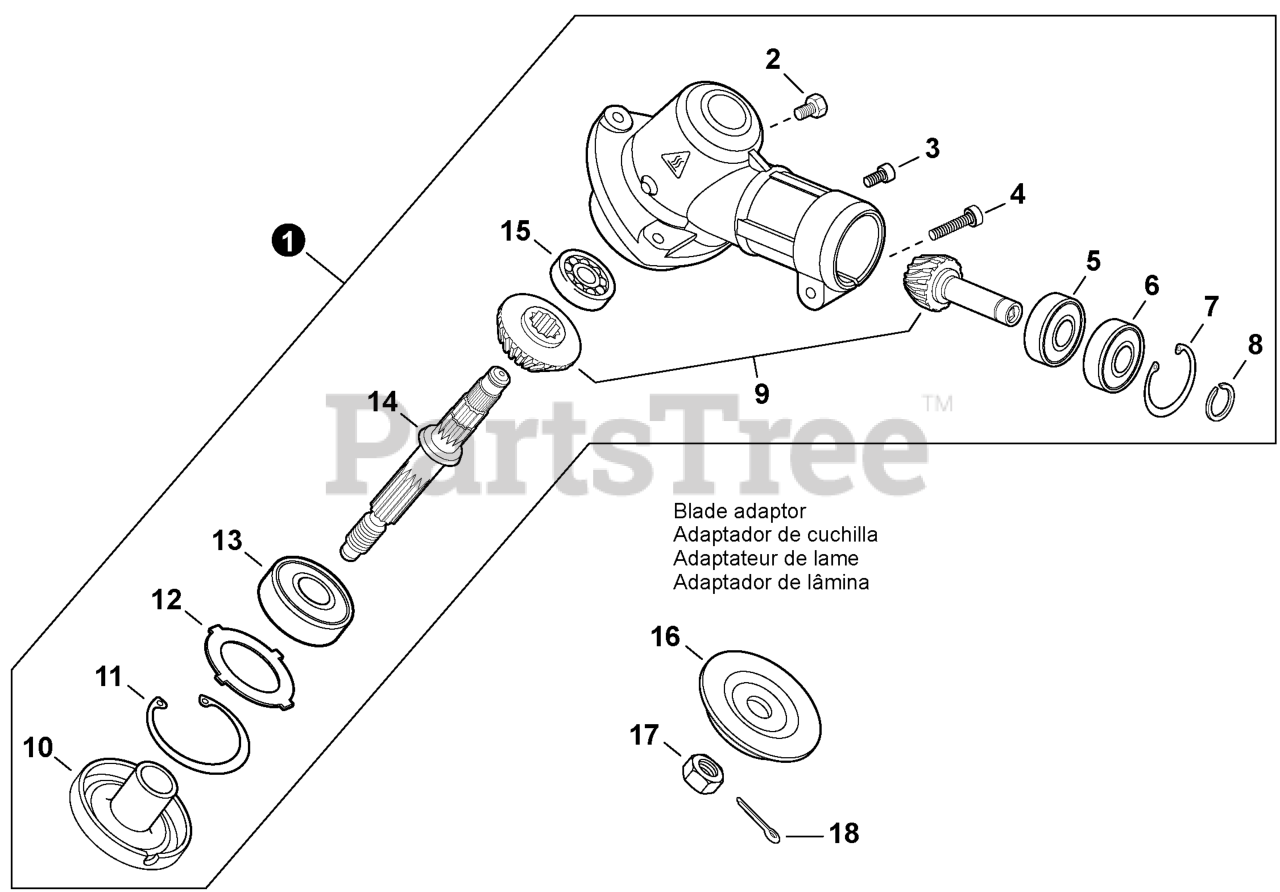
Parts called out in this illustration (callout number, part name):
1	GEAR CASE ASSY
2	BOLT M8x8
3	BOLT, TORX 5x12
4	BOLT, TORX 5x25
5	BEARING, BALL 609A
6	BEARING, BALL 609ZA
7	RING, SNAP 25
8	RING, SNAP 9
9	GEAR SET, BEVEL
10	PLATE, ADAPTOR - UPPER
11	RING, SNAP 32
13	BEARING, BALL 6201
14	SHAFT, GEAR
15	BEARING, BALL 629A
16	PLATE, ADAPTOR - LOWER
18	PIN, COTTER 2x22
